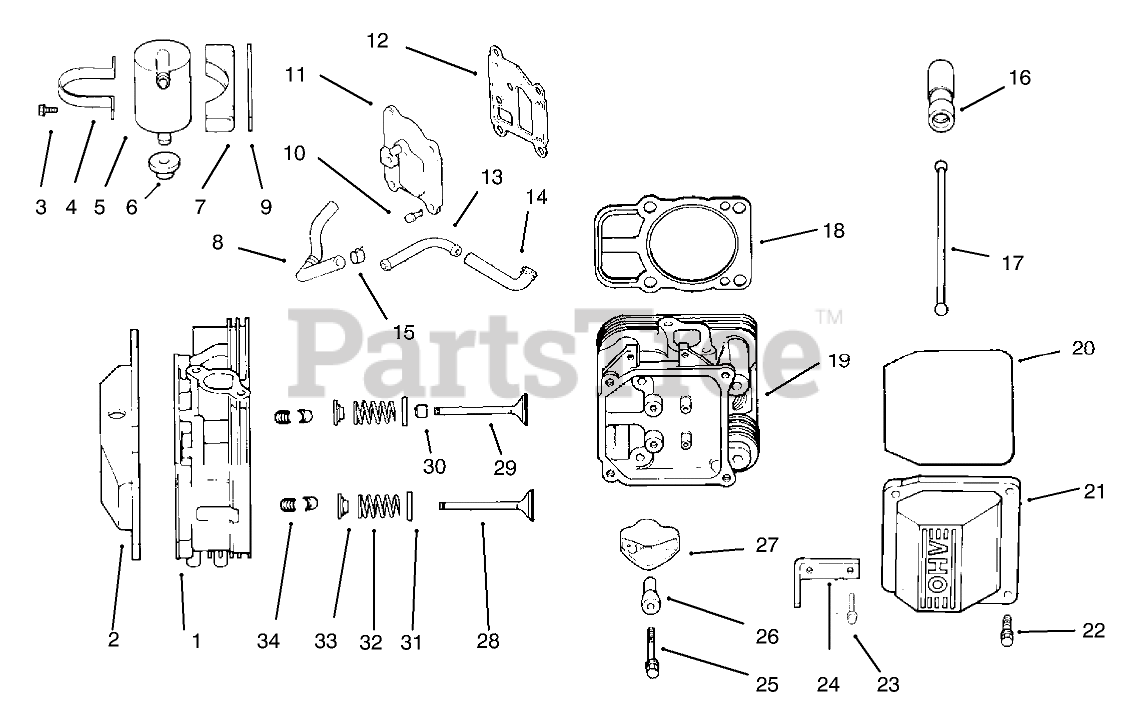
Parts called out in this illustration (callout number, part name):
1	#1 Cyl. Head Asm
2	Kit-Valve Incl 6 20-22
3	Screw-HF
4	Strap-Lifting
5	Kit-Breather Incl 3-9
6	Grommet-Rubber
7	Bracket
8	Hose-Breather
9	Spacer
10	Screw
11	Cover-Breather
12	Gasket-Breather
13	Fitting
14	Hose-Breather
15	Clamp
16	Lifter-Valve
17	Rod-Push
18	Gasket-Cylinder Head
19	#2 Cyl. Head Asm,
20	O Ring
21	Valve Kit
22	Screw
23	Screw
24	Strap-Lifting
25	Screw
26	Pivot-Arm, Rocker
27	Arm-Rocker
28	Valve-Exhaust
28	Valve-Exhaust (.25)
29	Valve-Intake
29	Valve-Intake (.25)
30	Seal-Stem, Valve
31	Retainer-Spring
32	Spring-Valve
33	Cap-Spring, Valve
34	Retainer Kit
